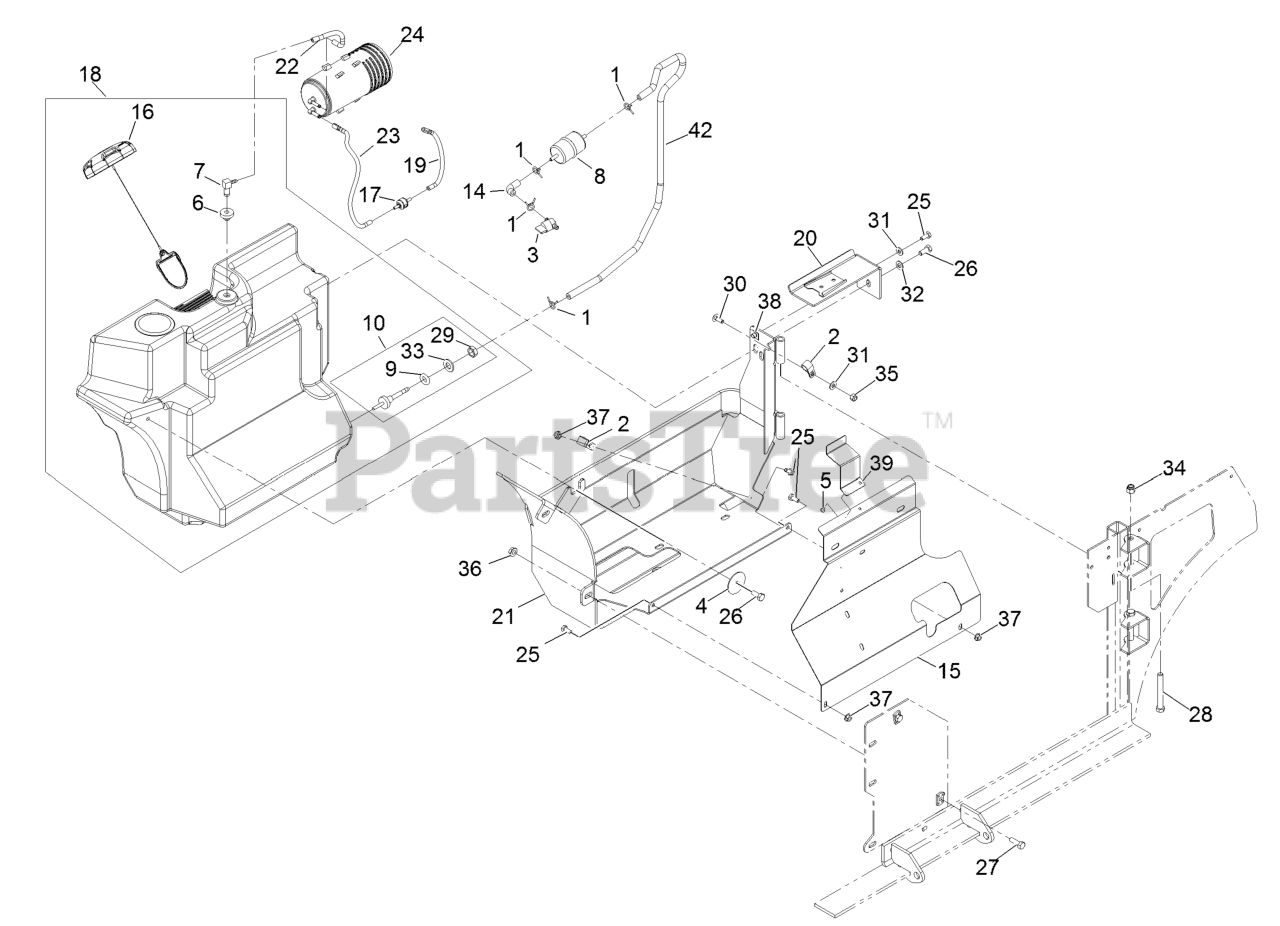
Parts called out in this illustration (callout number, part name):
2	CLIP-LOOM
3	VALVE-FUEL
5	RIVET-POP
6	BUSHING
8	Kohler Fuel Filter
9	O-RING,BULKHEAD FITTING
10	FITTING-FUEL, BULKHEAD
14	HOSE-FUEL
18	ASM-FUEL TANK
19	HOSE-VENT, FORMED
20	CANISTER BRACKET ASM
21	TANK FRAME ASM
22	HOSE-VENT, FORMED
23	HOSE-VENT, FORMED
24	CANISTER-CARBON, 800CC
25	SCREW-HH
26	SCREW-HH
27	SCREW-HH
28	SCREW-CARR
29	NUT-JAM
30	BOLT-CARR
31	WASHER-FLAT
32	WASHER-PLAIN
33	WASHER-FLAT
34	NUT-LOCK, NI
35	NUT-LOCK, NI
38	Nut-Retainer-Panel 1/4-20
39	Bracket-Tank Shield
42	HOSE-FUEL
